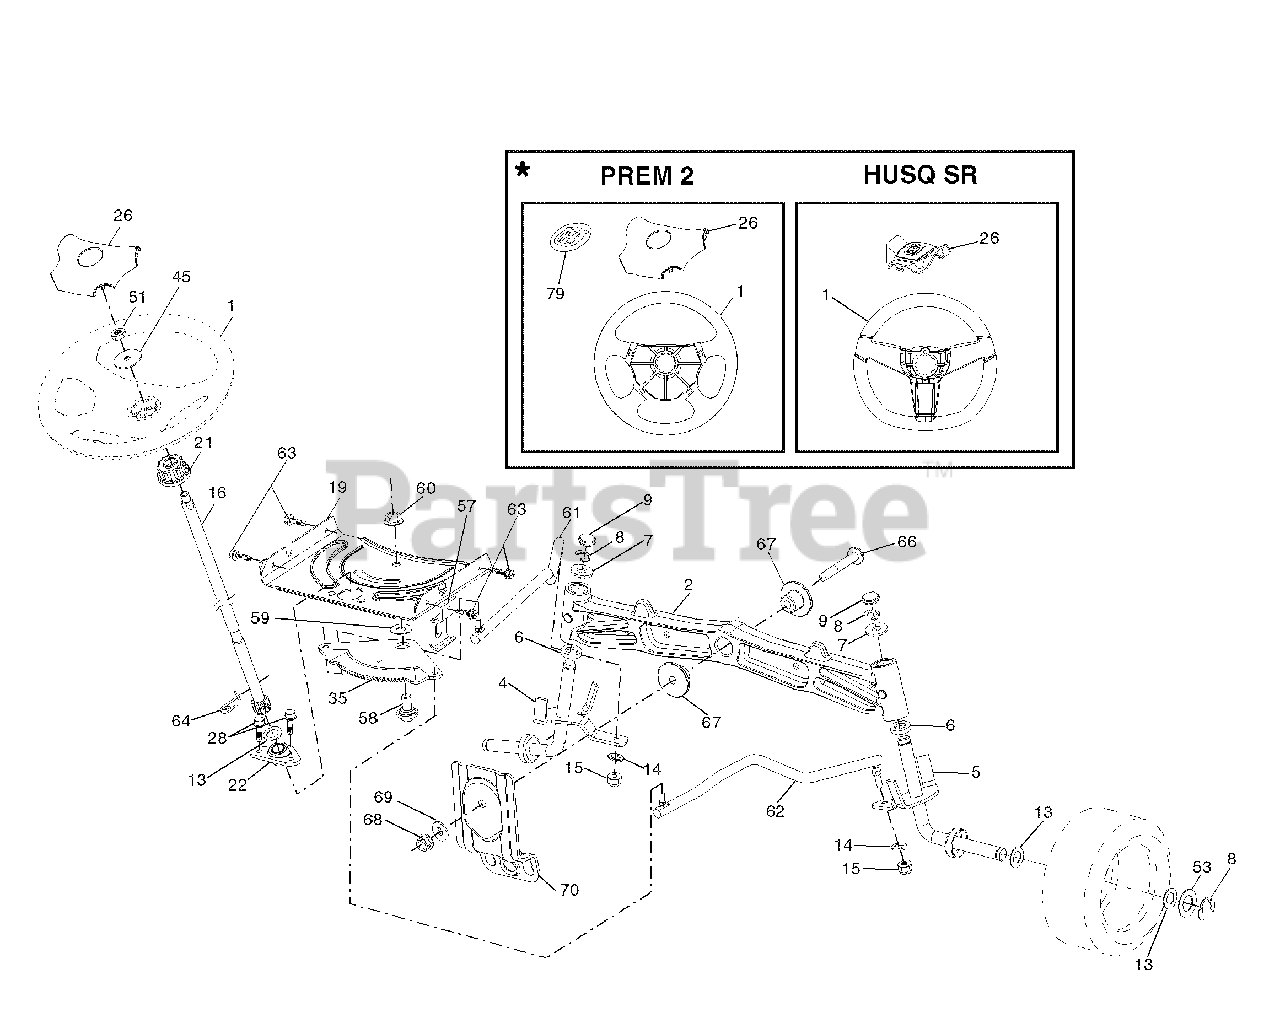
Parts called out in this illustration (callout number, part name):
1	Wheel, Steering
2	Axle Asm., Front
4	Spindle Asm. LH
5	Spindle Asm. RH
6	Bearing, Race Thrust Harden
7	Washer 25/32 x 1-5/8 x 16 Ga.
8	Ring, Clip #T5304-75
9	Cap, Spindle
13	Washer 25/32 x 1-1/4 x 16 Ga.
14	Washer, Lock Hvy Hlcl Spr 3/8
15	Nut, Crown Lock 3/8-24 unf
16	Shaft Steering
19	Plate Steering
21	Adapter, Wheel Steering
22	Bushing, Strg. Blk
26	Insert, Wheel Steering
28	Screw 3/8-16 x 3/4
35	Gear, Sector Plate
45	Washer 9/16 x 2-3/8 x 12 Ga.
51	Nut Hex Jam Toplock 1/2-20 unf
53	Washer Hardened .793 x 1.637 x .060
57	Bracket Upstop
58	Bolt Shoulder Sector Pivot CFM
59	Washer Thrust Sector Steering
60	Nut Flange Lock 5/8-11
61	Draglink LH
62	Draglink, RH
63	Screw 5/16-18 x 3/4
64	Retainer Clip Spring Steering
66	Bolt Hex Fghd 7/16-14 x 3 Serr
67	Bushing PM Front Axle
68	Nut Lock Flange 7/16-14 Gr. 5
69	Washer 1.5 x .505 x .118
70	Bracket Deck Susp. Front
